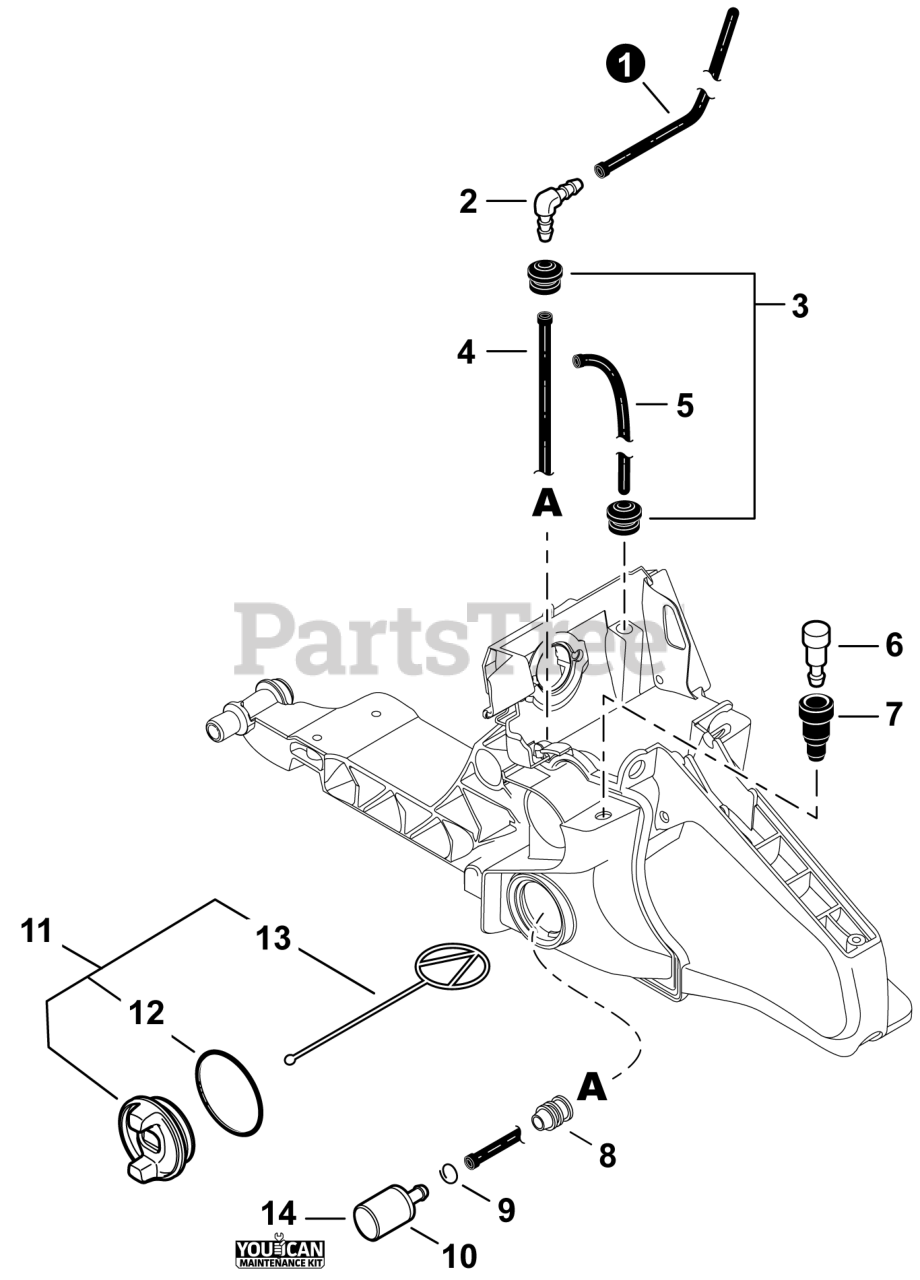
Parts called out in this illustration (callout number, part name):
1	PIPE, FUEL 3x6x135
2	CONNECTOR, PIPE
4	PIPE, FUEL 3x5x120 BLACK
5	PIPE, IMPULSE 3x6(8)x160
6	VENT ASSY
7	GROMMET, VENT
10	FILTER, FUEL
11	CAP ASSY, FUEL
12	O-RING 29
13	CONNECTOR, CAP L= 60 MM
14	TUNE-UP KIT - YOUCAN?
